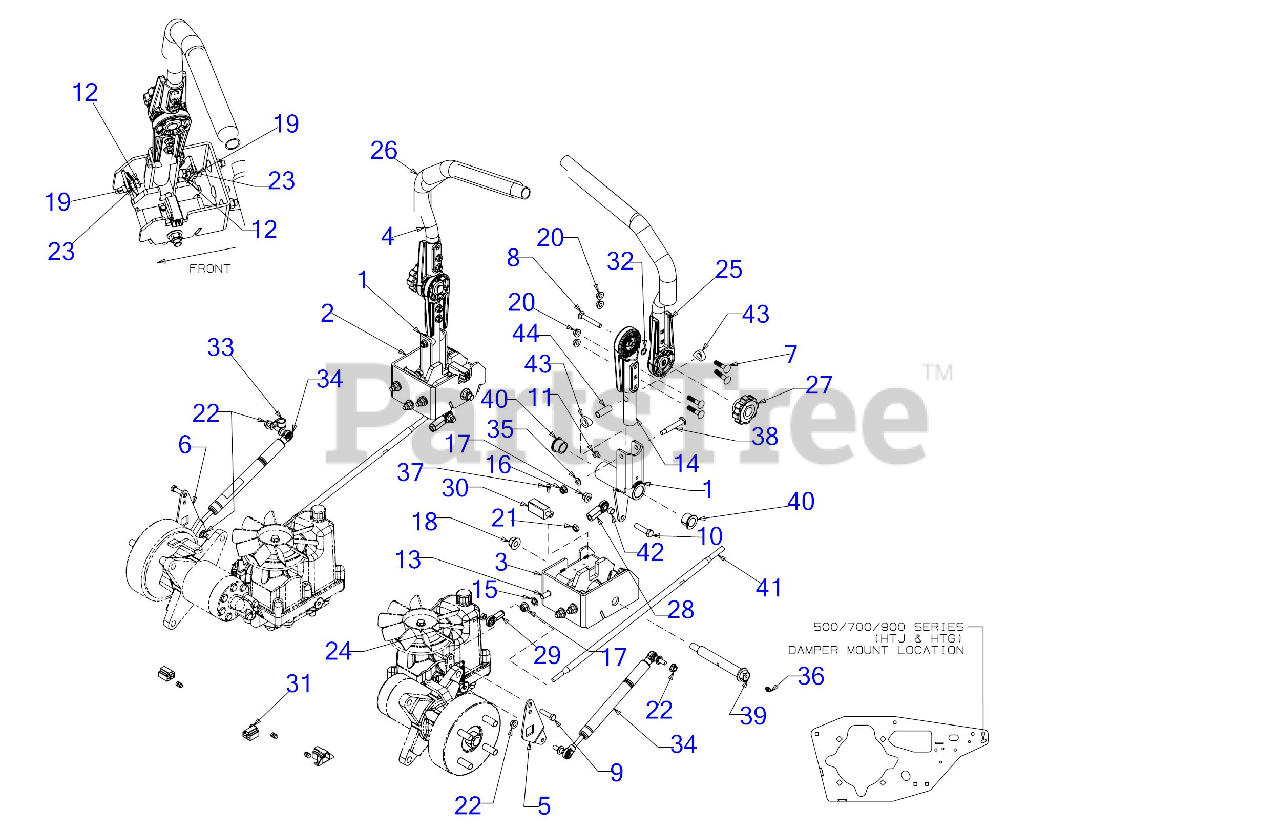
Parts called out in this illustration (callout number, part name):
1	LAPBAR PIVOT CONTROL ASSEMBLY
5	MOUNTING BRACKET (RH)
6	MOUNTING BRACKET (LH)
7	CARRIAGE BOLT 5/16-18 x 1.50
8	SCRE W5/16-18 x 2.25 GR5
9	SCREW 5/16-18 x 1.25 GR5
10	SCREW 3/8-16 x 1.50 GR8
11	SCREW 1/4-20 x .375
12	SCREW 3/8-16 x 1.25 GR5
13	CARRIAGE BOLT 3/8-16 x 1.00 GR5
16	FLANGE LOCK NUT 5/16-18
19	U NUT 3/8-16
20	FLANGE NUT
21	HEX JAM NUT 3/8X24
22	HEX FLANGE NUT
24	HEX NUT TOP LOCK 5/16-18 GR 8
25	HANDLE ADJUST
27	KNOB-5/16-18
28	BALL JOINT
29	END ROD- 5/16 (LH)
30	INTERLOCK SWITCH (NO/NC)
31	ADAPTER HARNESS - LAPBAR
34	DAMPENING CYLINDER
35	FLAT WASHER
36	GREASE ZERT 1/4-28
37	SHOULDER SCREW
38	SHOULDER SCREW
39	SHOULDER BOLT 1.0 X 4.75 1/2-13
40	FLANGE BEARING
43	NYLON SPACER
